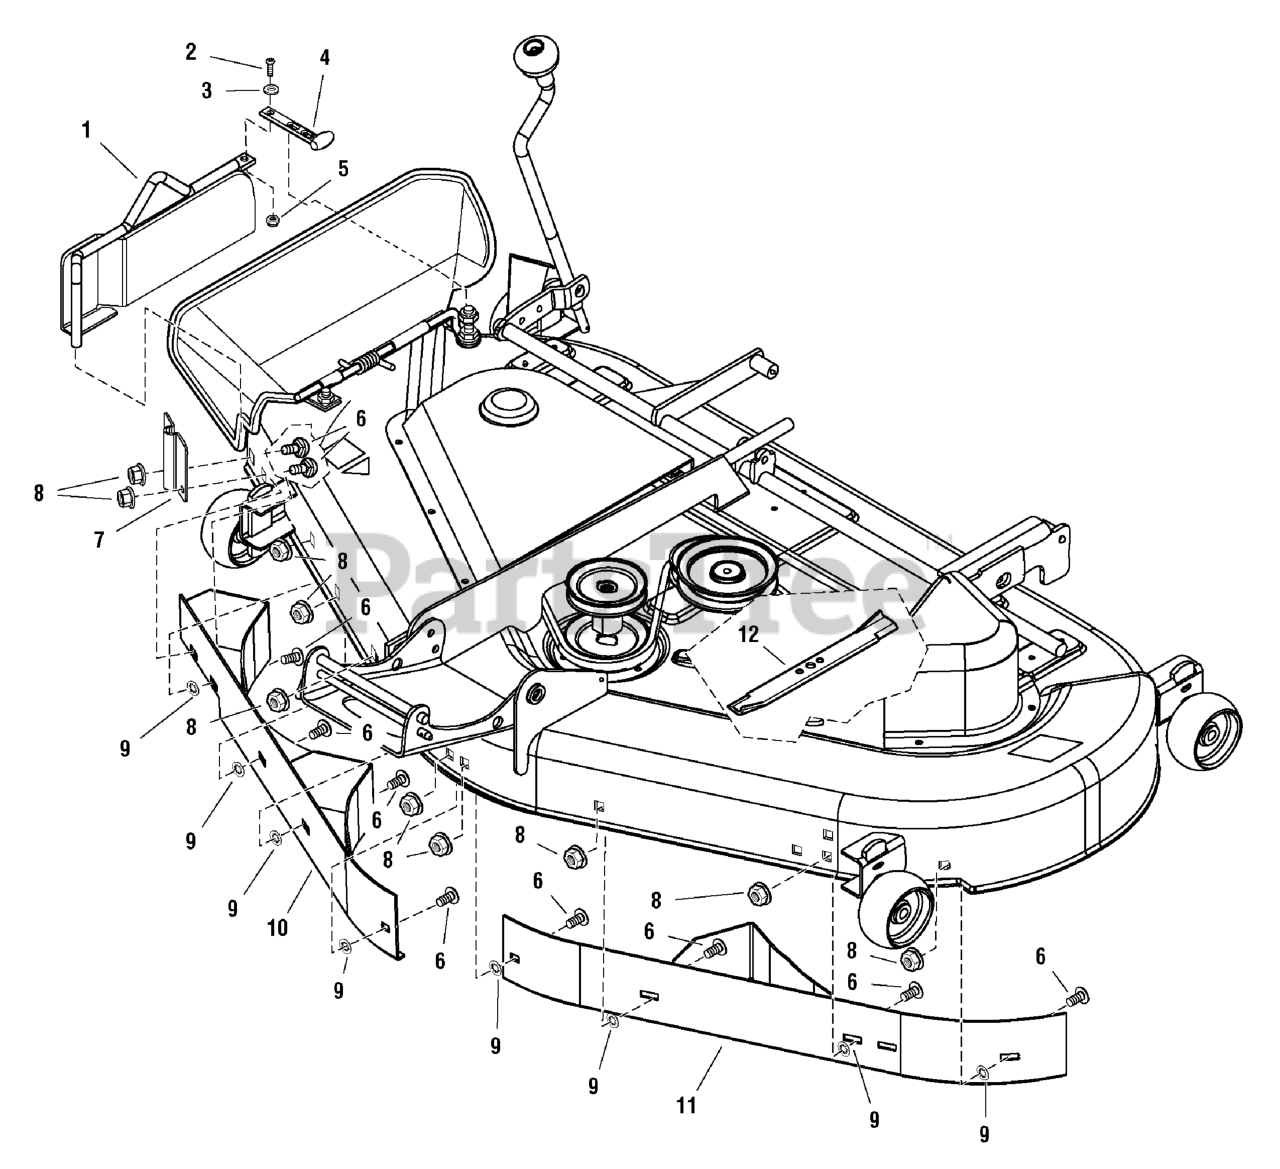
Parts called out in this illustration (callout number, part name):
1	BAFFEL ASSEMBLY
2	SCREW, Phillips, Pan Head, #10-24 x 1
4	STRAP, Rubber
5	NUT, Hex, Nylock, #10-24
6	CARRIAGE BOLT, 5/16-18 x 5/8
7	PLATE, Mounting
8	NUT, Hex, Flange Lock, 5/16-18
9	NUT, Push, 5/16
10	BAFFLE & DEFLECTOR, RH
11	BAFFLE & DEFLECTOR, LH
12	BLADE, Mower
